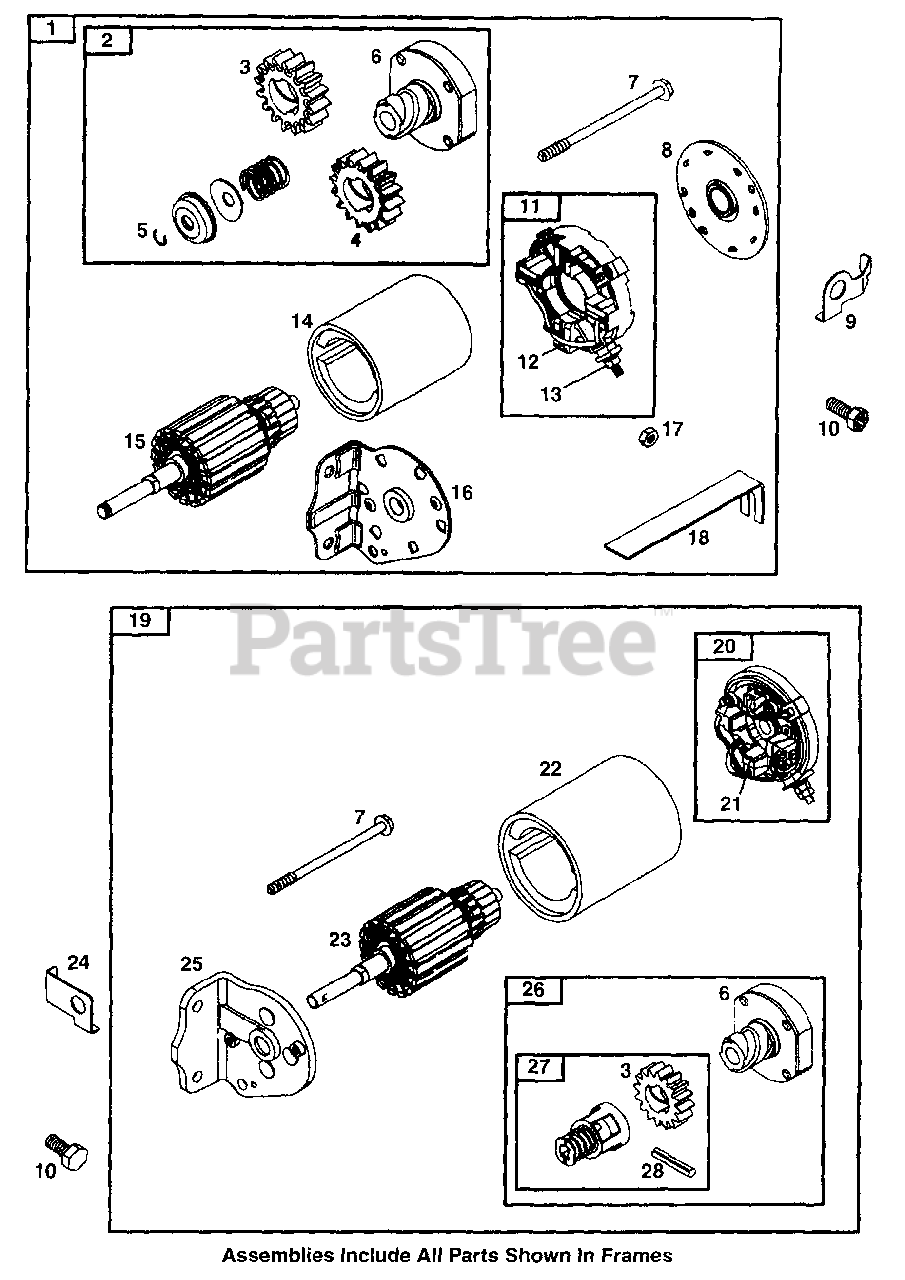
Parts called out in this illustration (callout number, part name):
1	Starter (3 5/8 Hsg, Aluminum Ring Gear)
2	Starter Drive
3	Starter Gear (for Plastic Ring Gear Only),
4	Pinion Gear (Aluminum Ring Gear Only)
5	Retaining Ring
6	Starter Assembly Clutch
7	Hex Washer Hd Screw (4 3/8" Housing)
10	Hex Head Torque Screw
11	Brush Retainer
14	Housing Assembly (3 5/8" Housing)
15	Armature Assembly (3 5/8" Housing)
16	Drive Cap
17	Hex Nut, 1/4-20
18	Ground Strap (4 3/8" Housing)
19	See Ref #1 for Replacement Starter
20	End Cap (3 5/8" Housing)
22	Starter Housing (3 5/8" Housing)
23	Armature Assembly (3 5/8" Housing)
24	Wire Retainer
26	Starter Drive (4 3/8" Housing)
27	Gear Kit (4 3/8" Housing)
28	Spiral Pin, Copper
